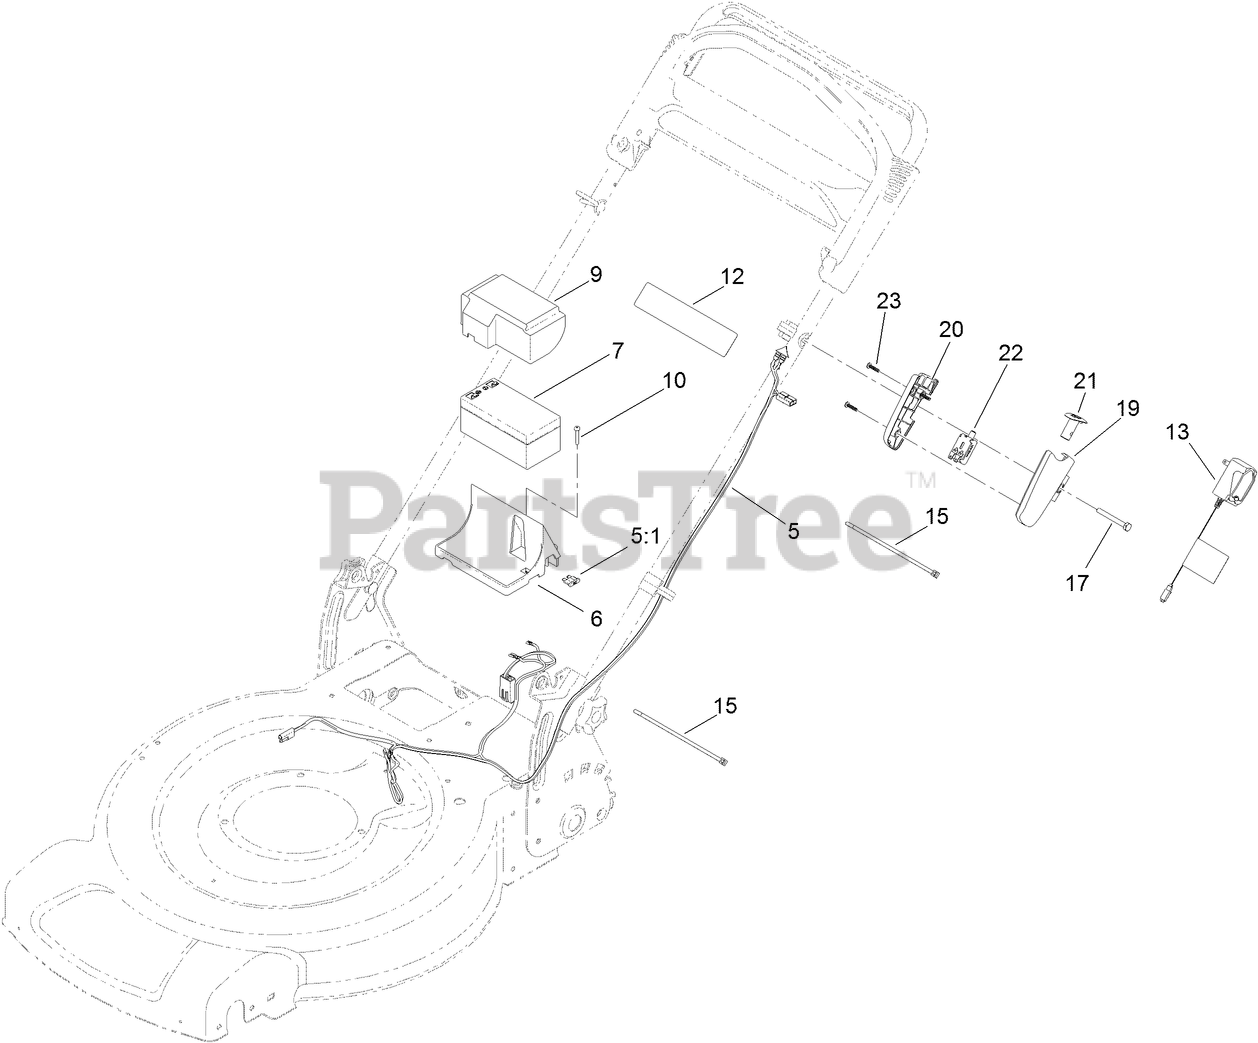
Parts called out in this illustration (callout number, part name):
5	HARNESS-WIRE
5:1	FUSE-40 AMP
6	TRAY-BATTERY
7	BATTERY-WET
9	COVER-BATTERY
10	SCREW-PPH, PLASTITE
12	DECAL-WARNING
15	TIE-CABLE
17	SCREW-HH
21	BUTTON-SWITCH
22	SWITCH-PUSH BUTTON
23	SCREW-PPH
